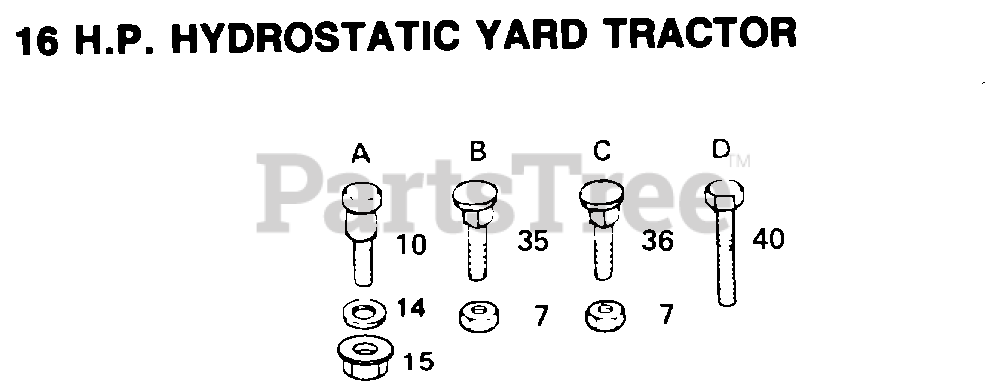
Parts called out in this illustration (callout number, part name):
10	"BOLT, SHOULDER LT"
14	WASHER T
15	NUT SPECIAL T
36	BOLT
40	"BOLT,HEX"
